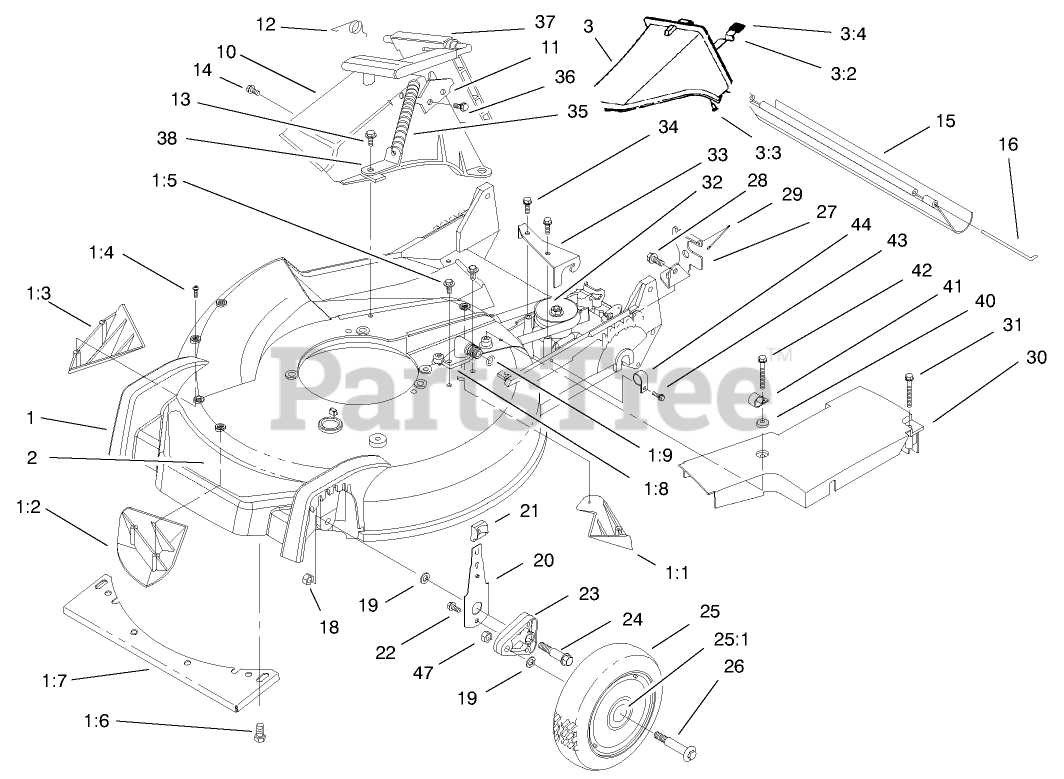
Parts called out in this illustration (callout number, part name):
1:1	KICKER-REAR
1:2	KICKER-FRONT
1:3	KICKER-RH
1:4	SCREW-PPH
1:5	SCREW-HWH
1:6	SCREW-HWHTF
1:9	O-RING
3	DISCHARGE PLUG ASM
3:2	LATCH-PLUG, DISCHARGE
3:3	RIVET-HEAD, FLAT
3:4	GRIP-LATCH
10	TUNNEL-DISCHARGE
11	LATCH-PLATE
12	RETAINER-DOOR
14	SCREW AND WASHER ASM
16	ROD-SHIELD
18	NUT-LOCK
19	WASHER
20	FRONT SPRING ARM ASM
21	KNOB-ARM
22	SCREW-HWH
23	ARM-PIVOT, FRONT
24	BOLT-SHOULDER
25	WHEEL ASM
25:1	BUSHING
26	BOLT-SHOULDER
28	SCREW-HWHTF
29	RETAINER-CABLE
31	SCREW-HWH
32	GEARCASE ASM
34	SCREW-HWHTF
35	SPRING-DOOR
36	SCREW-PLASTITE
37	DISCHARGE DOOR ASM
38	BRACKET-SPRING
40	WASHER
41	CLAMP-CABLE
42	SCREW-SPECIAL
43	SCREW-HWH
44	CLAMP-CABLE
47	LOCKNUT
